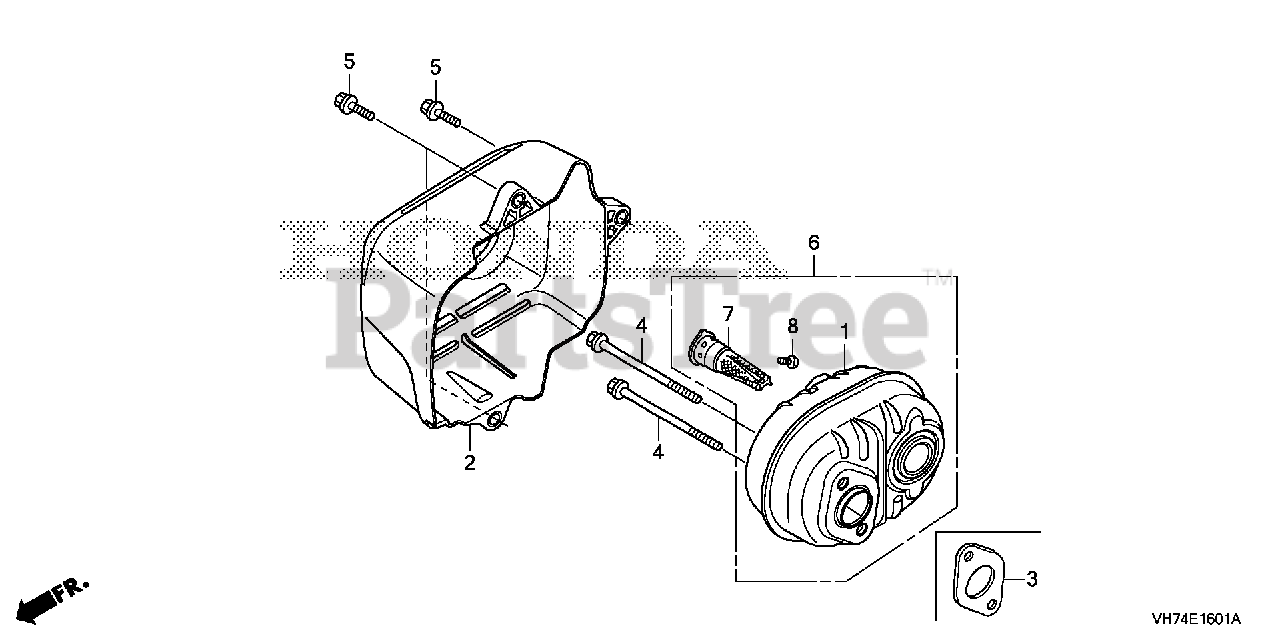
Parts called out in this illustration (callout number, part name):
2	PROTECTOR, MUFFLER
3	GASKET, MUFFLER
4	BOLT, FLANGE (6X79) (CT200)
5	BOLT, FLANGE (6X23)
6	MUFFLER ASSY. (ARRESTER)
7	ARRESTER, SPARK
8	SCREW, TAPPING (4X6) (TO INSTALL OPTIONAL SPARK ARRESTER)
